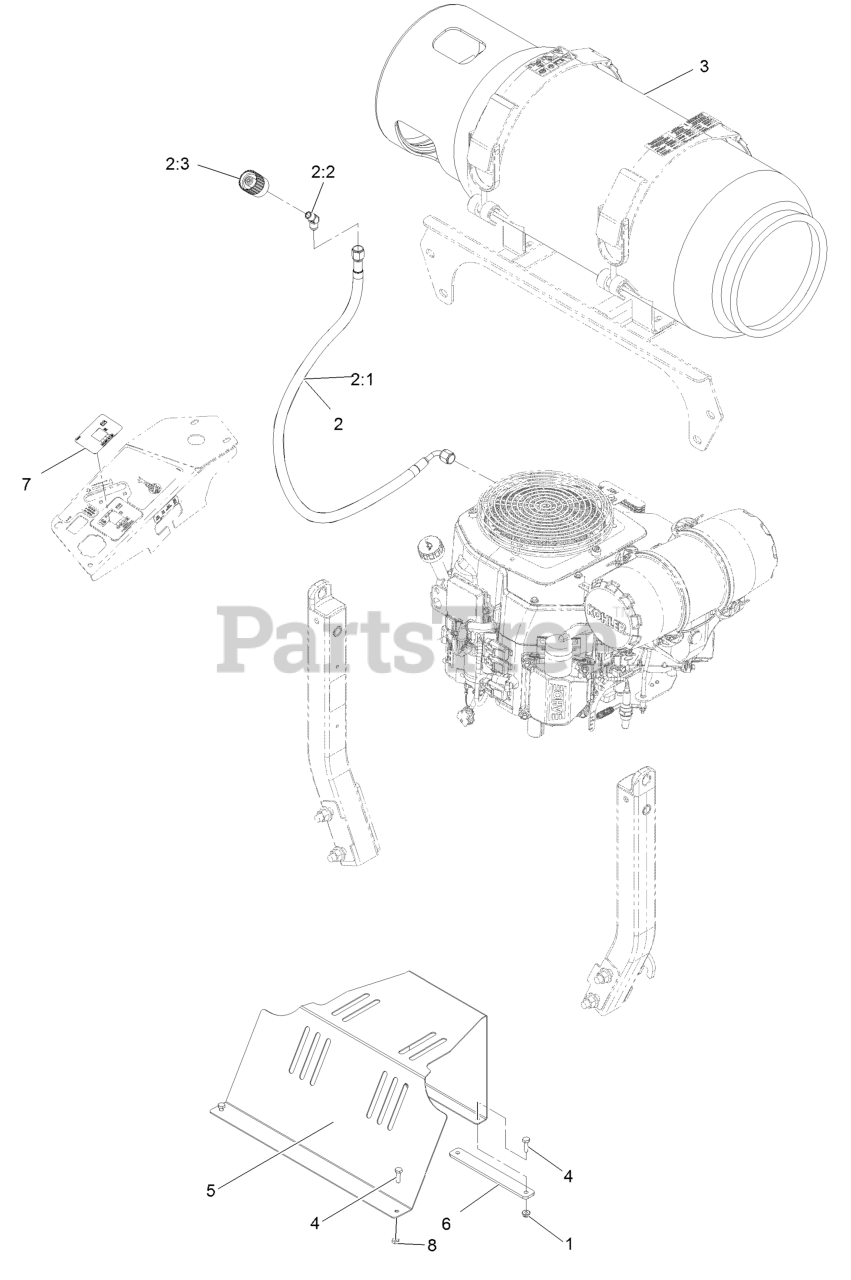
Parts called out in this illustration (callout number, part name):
2:1	LPG FUEL HOSE ASM
2:2	ELBOW-45 DEG
2:3	CONNECTOR-LPG TANK, LH TH
3	TANK-LPG
4	SCREW-HH
5	SHEILD-FAN
7	DECAL-METER, HOUR
8	NUT-JAM
